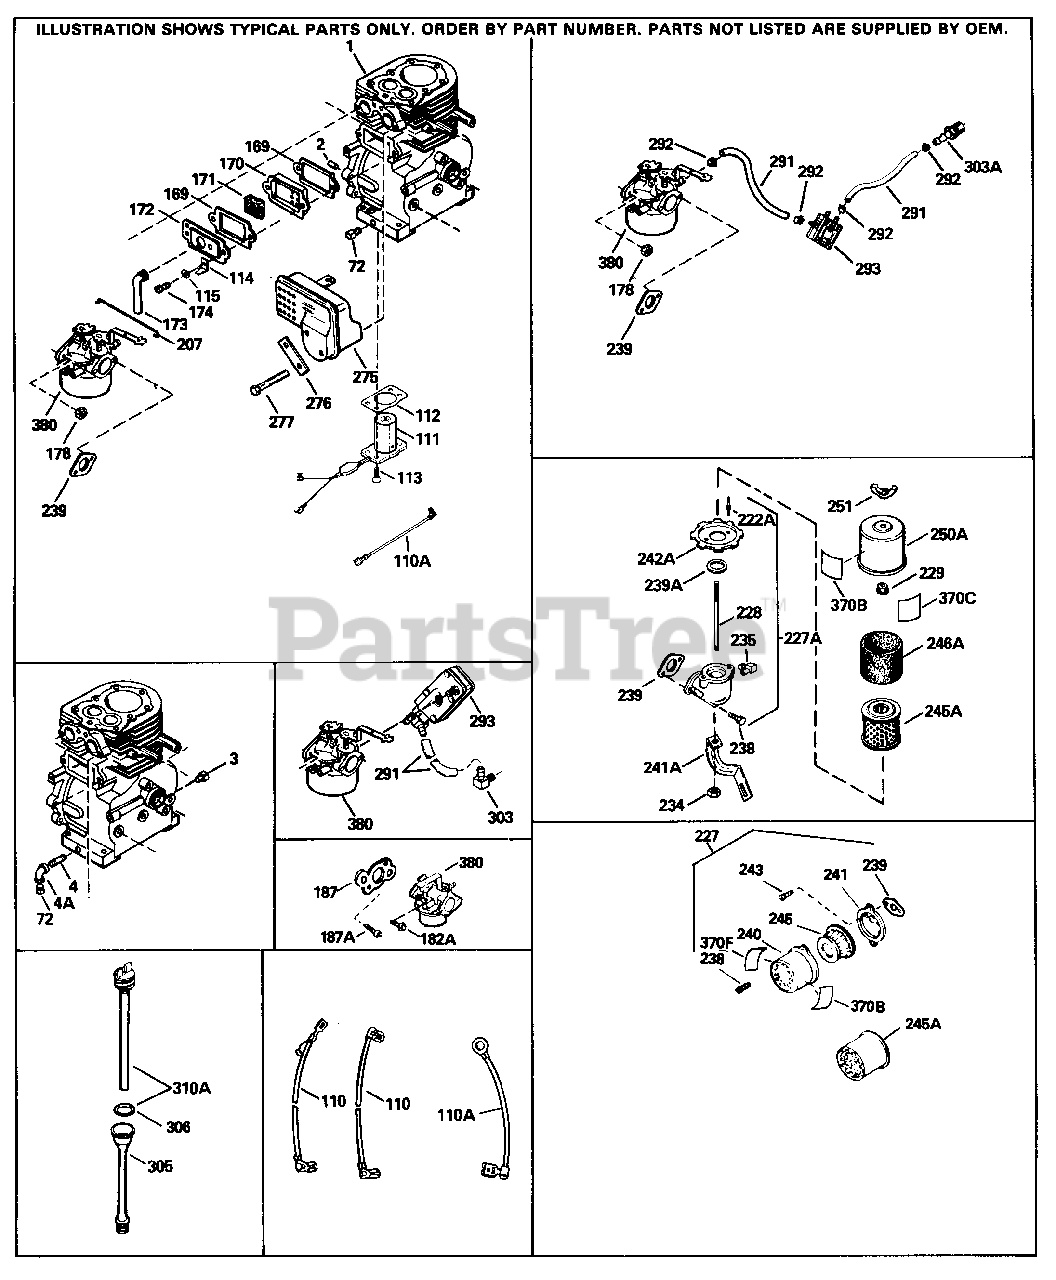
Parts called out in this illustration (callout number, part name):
1	"Cylinder Ass'y. (Incl. 2, 20, 72 & 72 A) (3-1/8" Bore) Bore)
2	Dowel Pin
3	Screw, 1/4-20 x 1/2"
4	Nipple, Pipe
72	Oil Drain Plug (Sq. hd., 1/4-18)
110	Ground Wire (One male, One female, On e eyelet)
169	* Gasket, Breather cover
170	Breather Body
171	Breather Element
172	Valve Cover
173	Breather Tube
178	Nut & Lock Washer 1/4-28
207	Link, Governor-to-throttle
227	Air Cleaner Ass'y. (Incl. 238, 239, 2 40, 241, 243, 245 & 370)(Use as requi red)
227	Air Cleaner Ass'y. (Incl. 238, 239, 2 40, 241, 243 & 245) (Use as required)
228	Stud, 1/4-20 x 7.33 (Use as required)
228	Stud, 1/4-20 x 8.1 (Use as required)( Used with drilled thru elbow)
275	Muffler
276	Muffler (Incl. 276)
277	Screw, 5/16-18 x 4-3/16"
291	Fuel Line (8.62")
292	Fuel Line Clamp
305	Oil Fill Tube
306	"O" Ring
370B	Decal, Instruction Can be used on HM8 0 with stamped steel recoil starter.
370C	Decal, Primer
370J	Decal, Instruction Can be used on HM8 0 with diecast starter.
380	Carburetor (Incl. 184) (Refer to Divi sion 5, Section A, page A3-10 for bre akdown or Fiche 18A-2, Grid F-3)
999	Winter Maintenance Kit incl. 5W30 Oil , Spark Plug, Key, & Ultra-Fresh
999	Winter Maintenance Kit (incl. 0W30 Sy nthetic Oil, Spark Plug, Key, & Ultra -Fresh)
